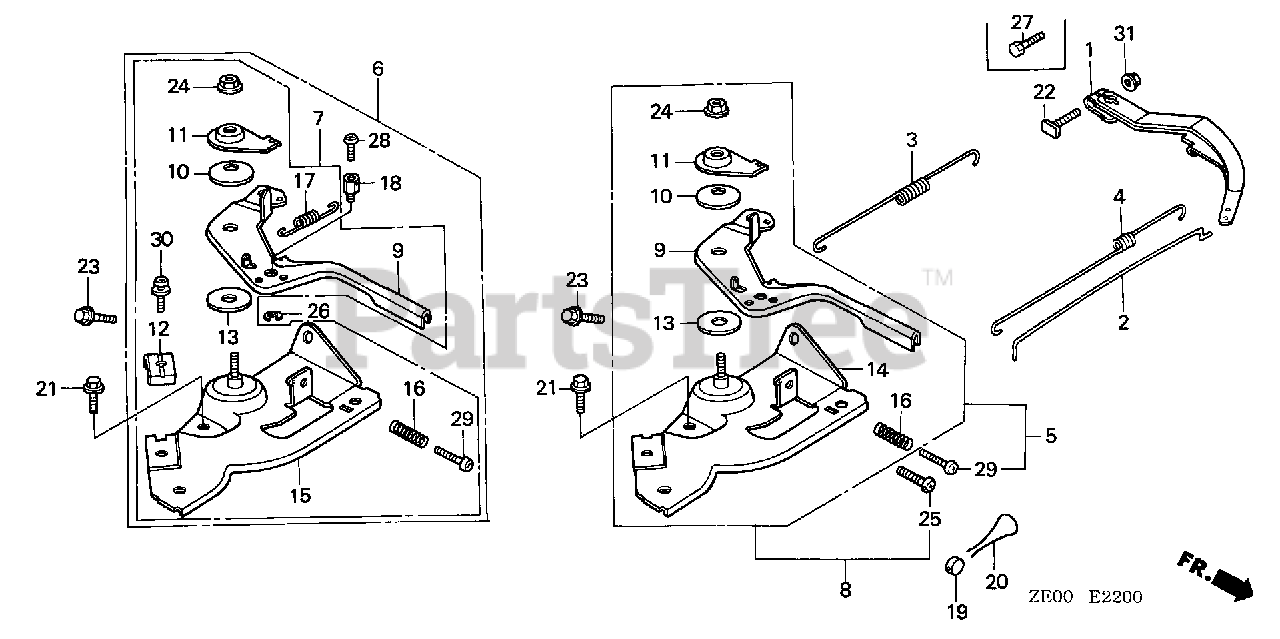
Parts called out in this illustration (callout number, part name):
1	ARM, GOVERNOR
2	ROD, GOVERNOR
3	SPRING, GOVERNOR
4	SPRING, THROTTLE RETURN
6	CONTROL ASSY. (CYCLONE)
9	LEVER, CONTROL
10	SPRING, LEVER
11	WASHER, CONTROL LEVER
12	HOLDER, CABLE
13	SPACER, CONTROL LEVER
15	BASE, CONTROL (CYCLONE)
16	SPRING, CONTROL ADJUSTING
17	SPRING, CABLE RETURN
18	HOLDER, WIRE
21	BOLT, FLANGE (6X12) (CT200)
22	BOLT, GOVERNOR ARM
23	BOLT, FLANGE (6X20) (CT200)
24	NUT, SELF-LOCK (6MM)
26	CIRCLIP (5MM)
28	SCREW, PAN (4X6)
29	SCREW, PAN (5X25)
30	SCREW-WASHER (5X16)
31	NUT, FLANGE (6MM)
